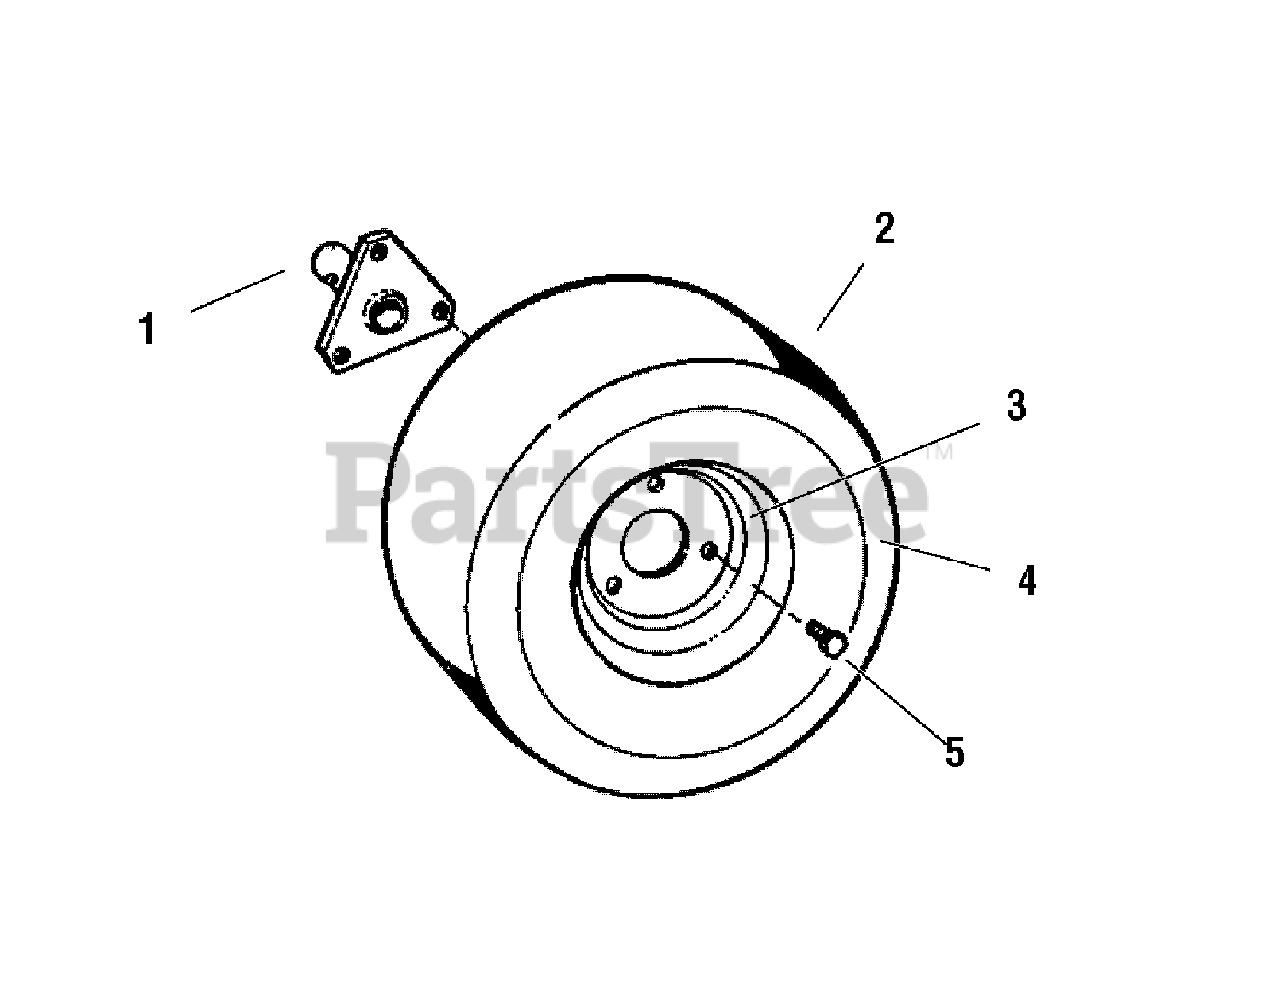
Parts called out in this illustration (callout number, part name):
1	WHEEL HUB ASSEMBLY
2	WHEEL & TIRE ASSEMBLY, Rear
3	WHEEL ASSEMBLY
4	TUBELESS TIRE
5	WHEEL HUB BOLT
